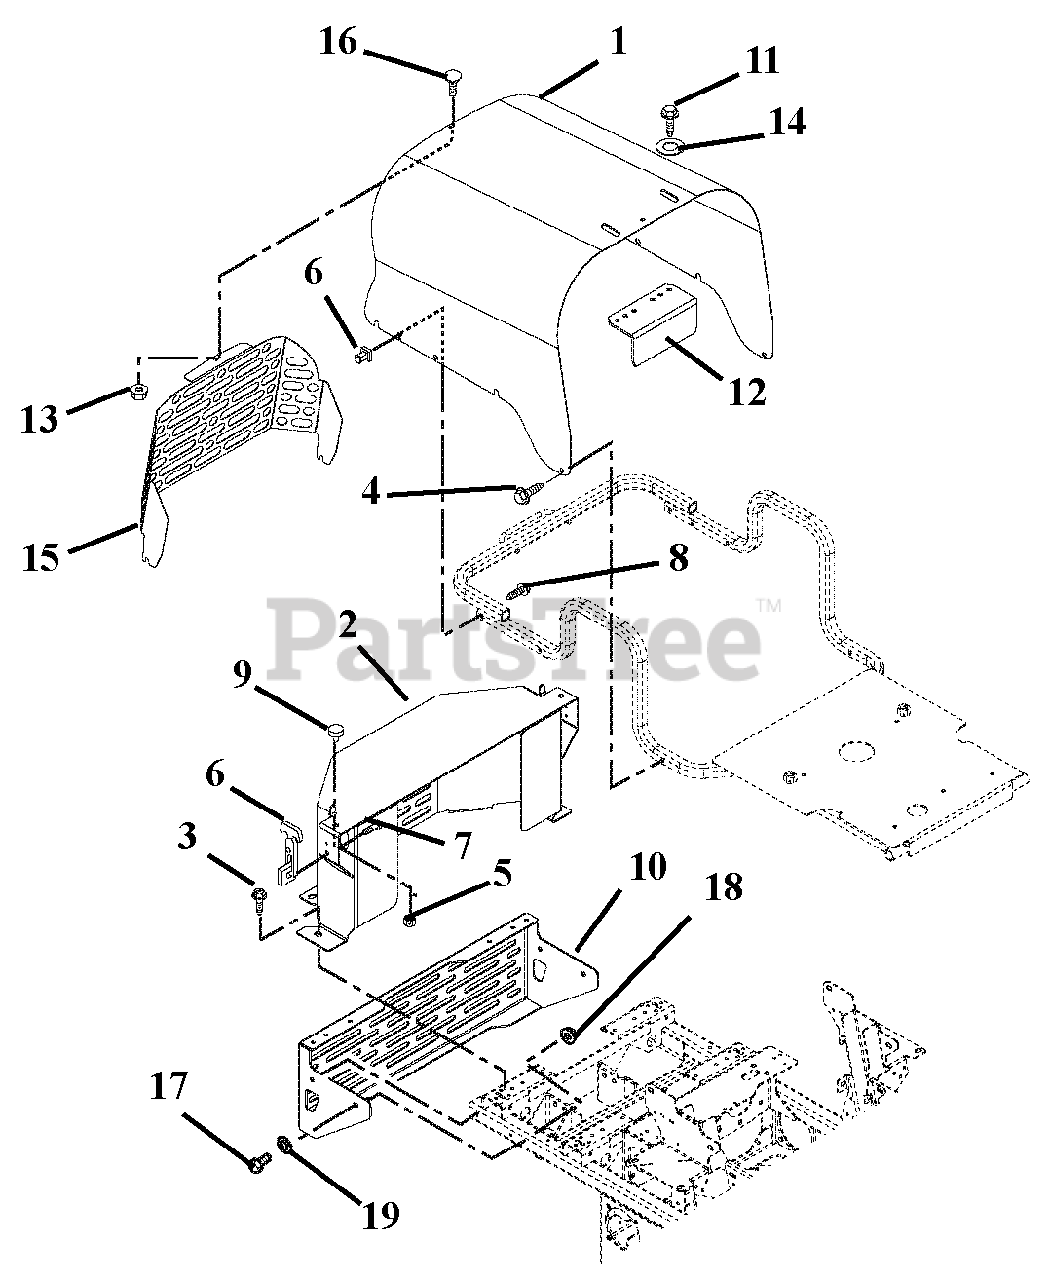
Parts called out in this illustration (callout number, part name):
2	Diesel Belt Guard
3	Screw, Tapping .38-16 x .75 Hex Washer Head
4	Screw, Tapping .38-16 x .50 Hex Washer Head
5	Nut, Spin Lock, Flange .312-18
6	Latch, Rubber
7	Screw, Machine 10-24 x .50 Hex Washer Head
8	Screw, Machine 10-24 x 1.50 Hex Washer Head
9	Bumper, Rubber
10	Bumper, Weldment, Rear Diesel
11	Screw, Tapping .25-20 x .50 Hex Washer Head
12	Guard, Radiator Cap
13	Nut, Locking Top Flange .25-20
14	Washer, Flat Steel .281 x .62 x .065
15	Guard, Hood
16	Bolt, Round Head Square Neck .25-20 x .50 Grade 5
17	Bolt, Hex .38-16 x 2.75 Grade 5
18	Nut, Locking Top Flange .38-16
19	Washer, Flat Steel .406 x .812 x.065
